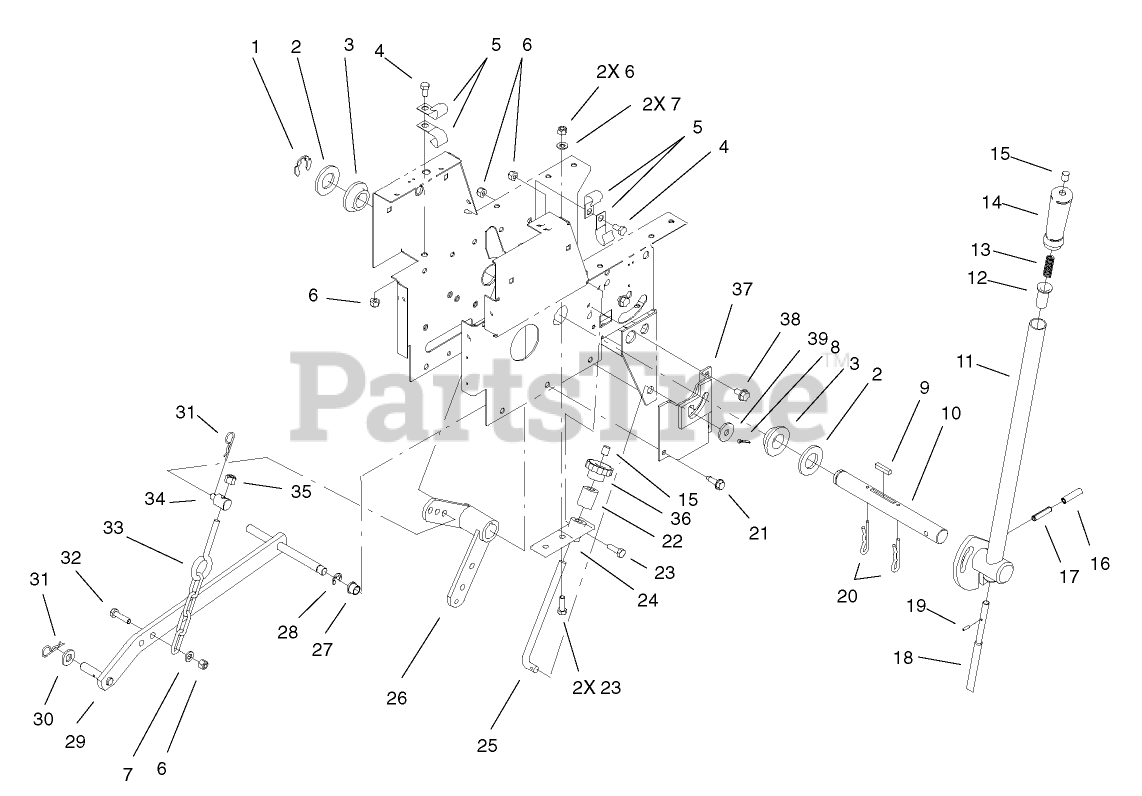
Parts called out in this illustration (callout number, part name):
1	RING-RETAINING
2	WASHER-FLAT
3	BEARING-FLANGE
4	SCREW-HH
5	CLIP
6	NUT-LOCK, NI
7	WASHER-PLAIN
8	PIN-COTTER
9	KEY-SQUARE
10	SHAFT-LIFT LEVER
11	LIFT HANDLE ASM
12	RETAINER-SPRING
13	SPRING-COMPRESSION
14	GRIP-HANDLE
15	CAP-ROD, PLUNGER
16	PIN-SPRING
17	PIN-ROLL
18	ROD-LATCH LIFT
19	PIN-SPIROL
20	PIN-HAIR
21	SCREW-TAPTITE
22	SLEV-LIFT ADJS
23	SCREW-HH
24	CASTING-LIFT LEVER
25	ROD-HEIGHT CONTROL
26	LIFT LEVER ASM
27	BUSHING
28	RING-RETAINING, EXTERNAL
29	LIFT BAR ASM
30	WASHER-FLAT
31	PIN-HAIR
32	SCREW-HH
33	CHAIN-LIFT
34	TRUNNION-LIFT
35	NUT-LOCK, NI
36	KNOB-LIFT CONTROL
37	LIFT LEVER ASM
38	SCREW-HWHTF
39	WASHER
